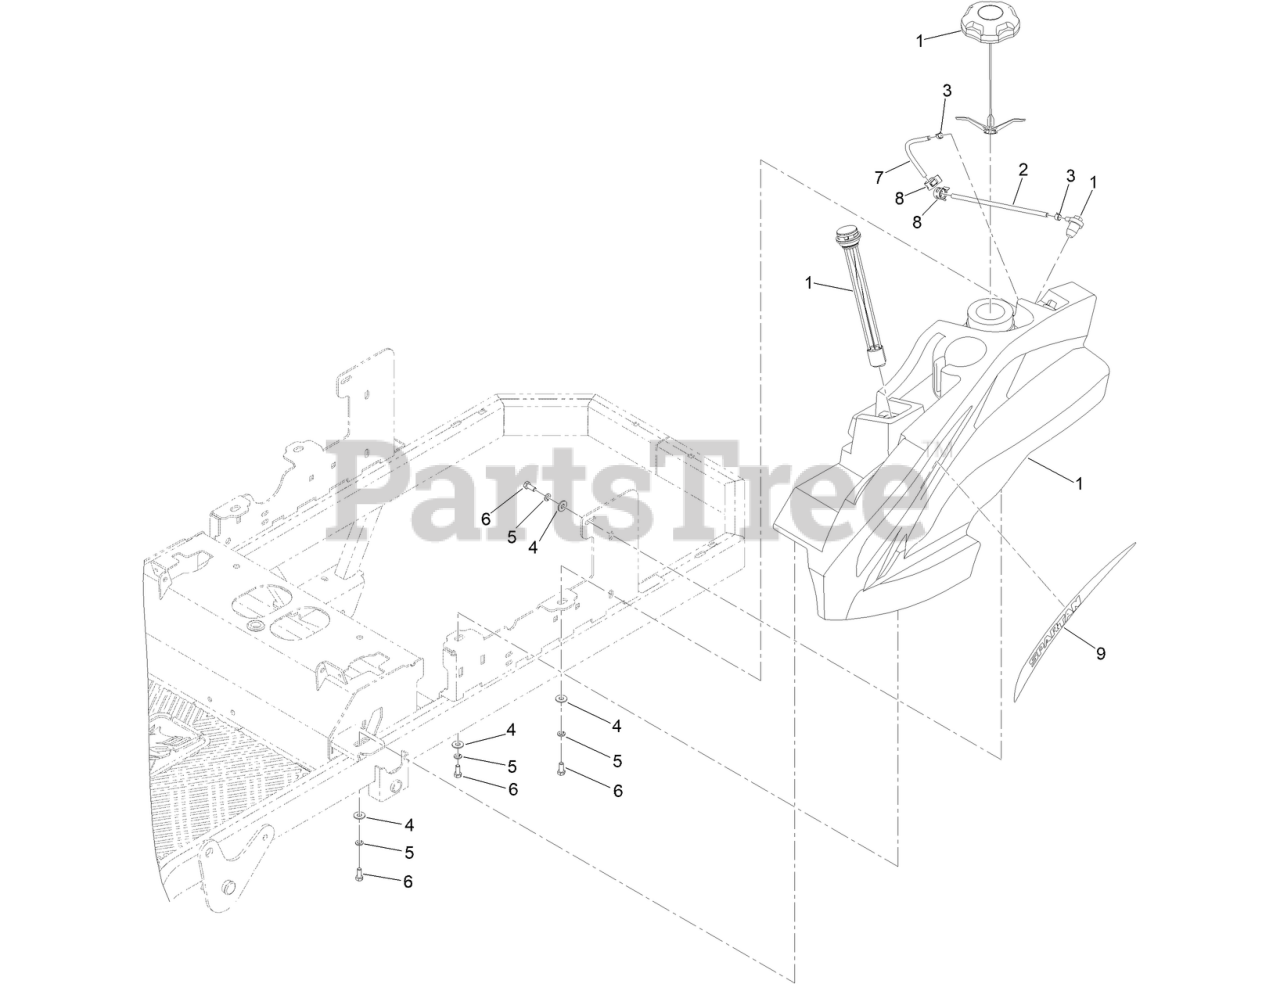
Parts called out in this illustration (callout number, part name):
1	2021 RZ MWR FUEL TANK ASSY LT
2	MWR FUEL TANK BLACK 3/16IN VENT TUBE 1FT
3	1/2IN (#8) HOSE CLAMP
4	WASHER-FLAT
5	WASHER-LOCK
6	SCREW-HH
7	1/4IN SAE J30R7 BULK HOSE 1FT
8	19MM HOSE CLAMP
9	2021 RZ FUEL TANK DECAL LT SIDE
